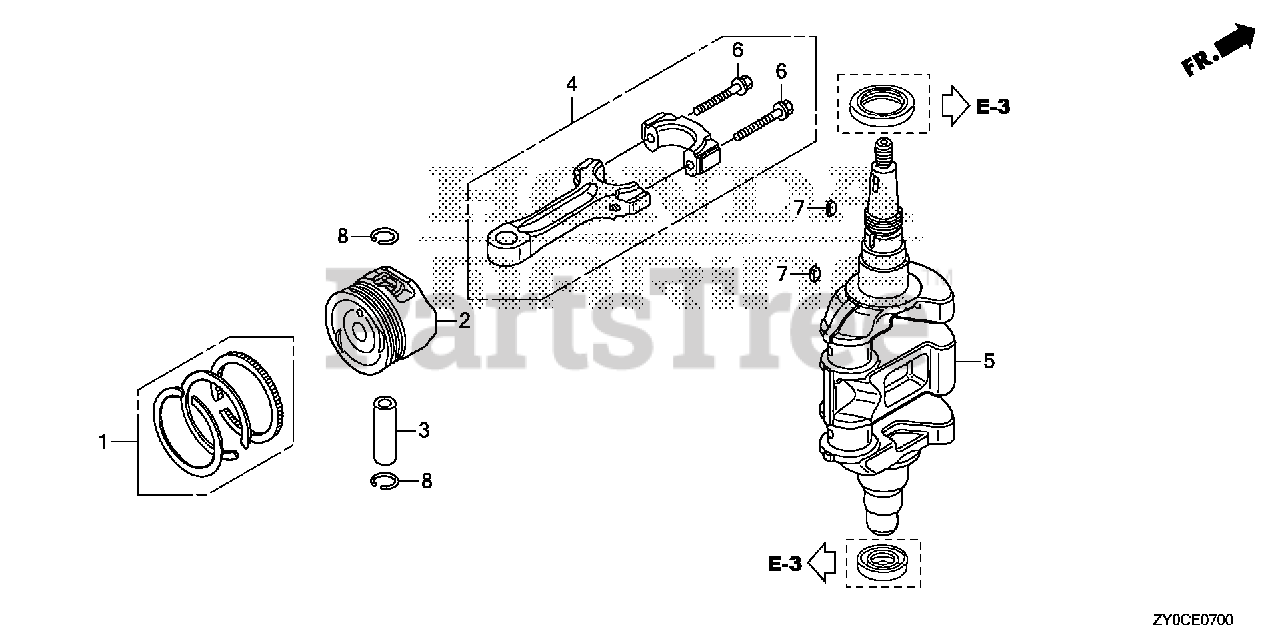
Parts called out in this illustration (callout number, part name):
1	RING SET, PISTON
3	PIN, PISTON
4	ROD, CONNECTING
5	CRANKSHAFT
6	BOLT, CONNECTING ROD (6X34)
7	KEY, SPECIAL (16X13)
8	CLIP, PISTON PIN (16MM)
